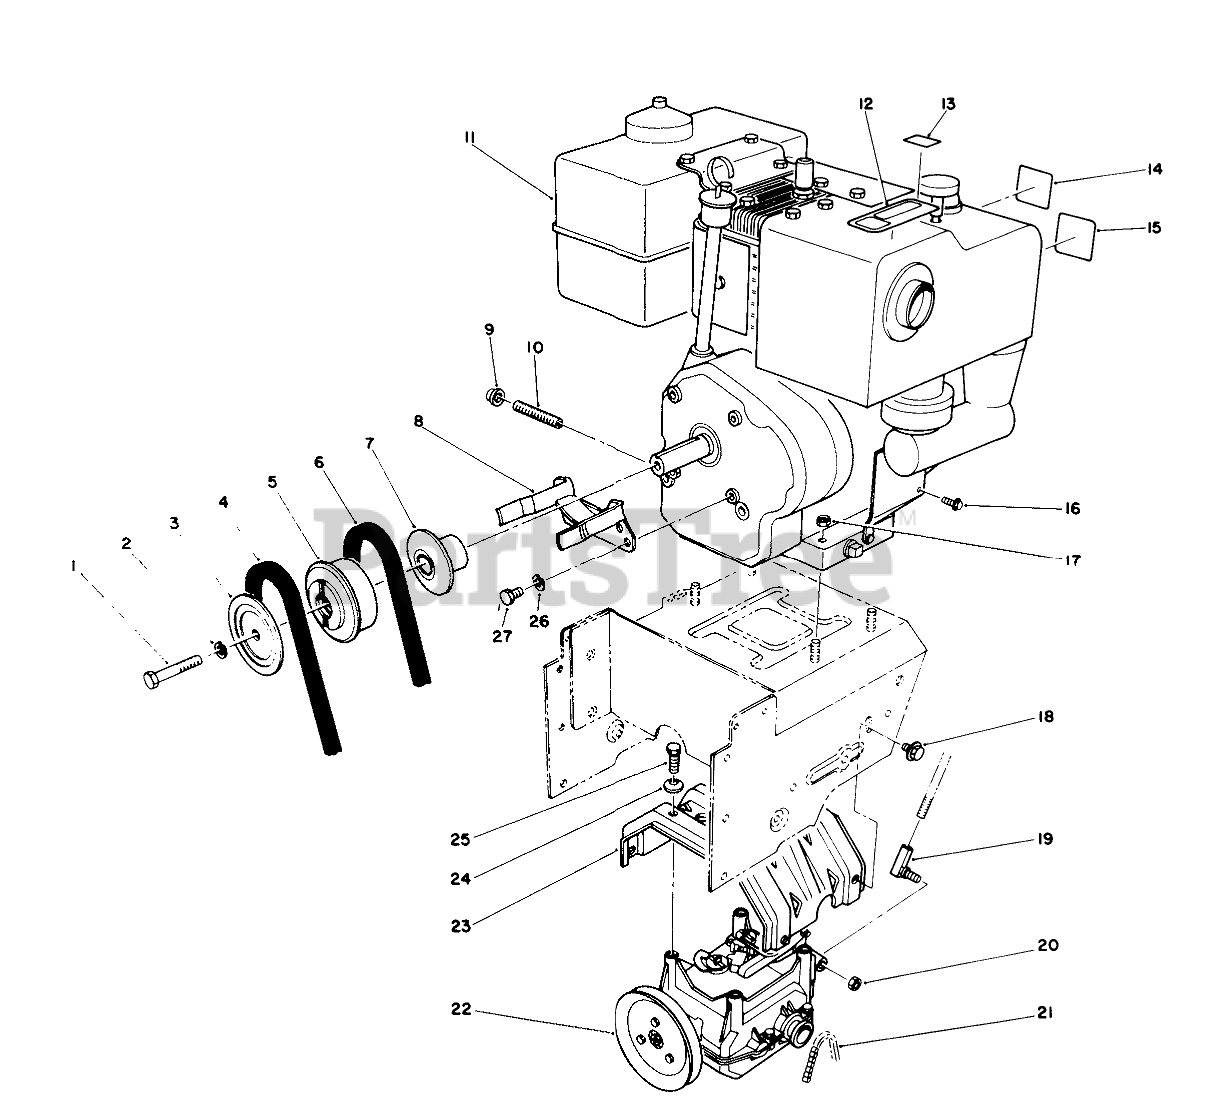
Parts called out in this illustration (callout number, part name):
1	SCREW-HH
2	WASHER-LOCK
3	SHEAVE-HALF, IMPELLER
4	V-BELT, IMPELLER
5	PULLEY-ENGINE, CENTER
6	V-BELT, TRACTION
7	SHEAVE-HALF, TRACTION
8	Guide-Belt
9	CAP-PIPE
10	NIPPLE-PIPE
12	Decal-Hot
13	DECAL - THROTTLE, INT'L
14	DECAL - PRIMER, INT'L
15	DECAL - CHOKE
16	SCREW-HH
17	NUT-HF
18	SCREW-HHF
19	JOINT-BALL
20	NUT-LOCK, NI
21	CHAIN
22	TRACTION GEARCASE ASM
23	Frame-Transmission
24	WASHER-SPRING
25	SCREW-HWHTF
26	WASHER-LOCK
27	SCREW-HH
